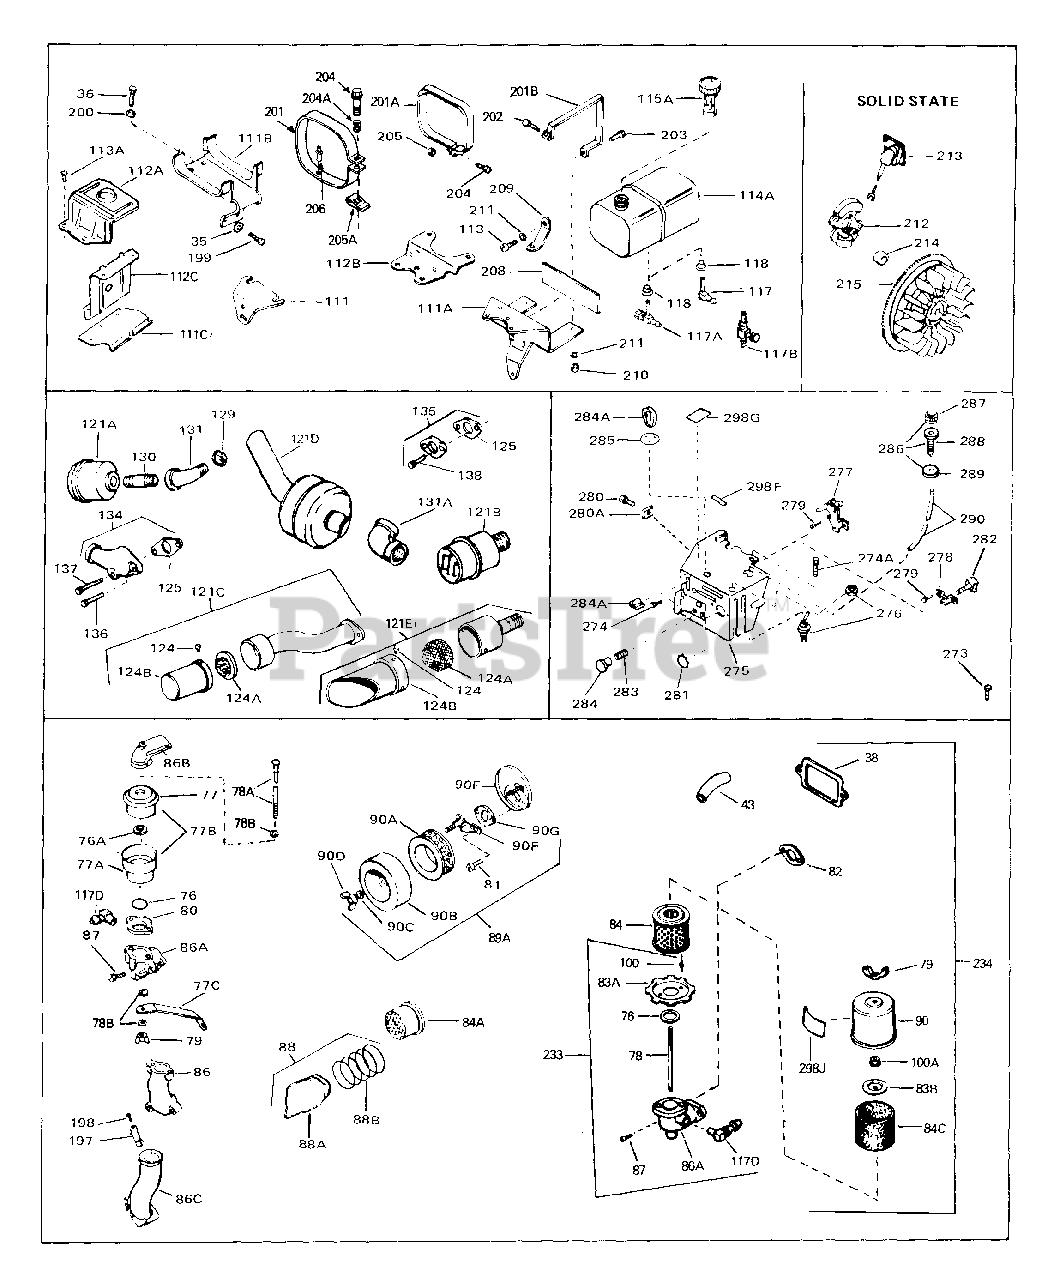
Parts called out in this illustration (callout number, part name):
35	Washer, Flat
36	Screw, Hex flange hd., 5/16-18 x 2
36	Screw, Hex flange hd., 5/16-18 x 2-1/ 4
36	Screw, Hex flange hd., 5/16-18 x 2-1/ 2
38	Gasket, Breather cover
43	Tube, Breather
81	Screw, Fil. hd. Sems, 10-32 x 1/2
81	Screw, Fil. hd., 5/16-18 x 3/4
81	Screw, Fil. hd. Sems, 10-32 x 1-1/8
82	Gasket, Air cleaner
86A	Elbow Assy., Air cleaner
89A	Cleaner Assy., Air
113	Screw, Hex hd. Sems. 1/4-20 x 1/2
117	Fitting, Fuel line
117B	Valve, Fuel strainer & shut-off
118	Bushing, Fuel fitting
121E	Muffler
124	Screw Hex hd. self-tap, 8-18 x 3/8
124A	Screen, Muffler
124B	Cover & Tube, Muffler
125	Gasket, Exhaust
129	Nut, Conduit (1/4" thick)
131	Elbow, Exhaust (45(deg))
134	Kit, Muffler adpater
135	Kit, Muffler adapter
136	Screw, Hex flange hd., 5/16-18 x 1-1/ 2
137	Screw, Hex flange hd., 5/16-18 x 2-1/ 2
138	Screw Fil hd., 5/16-18 x 3/4
233	Elbow Assy., Air cleaner
234	Air Cleaner Kit, Dual Element upright ,
273	Screw
